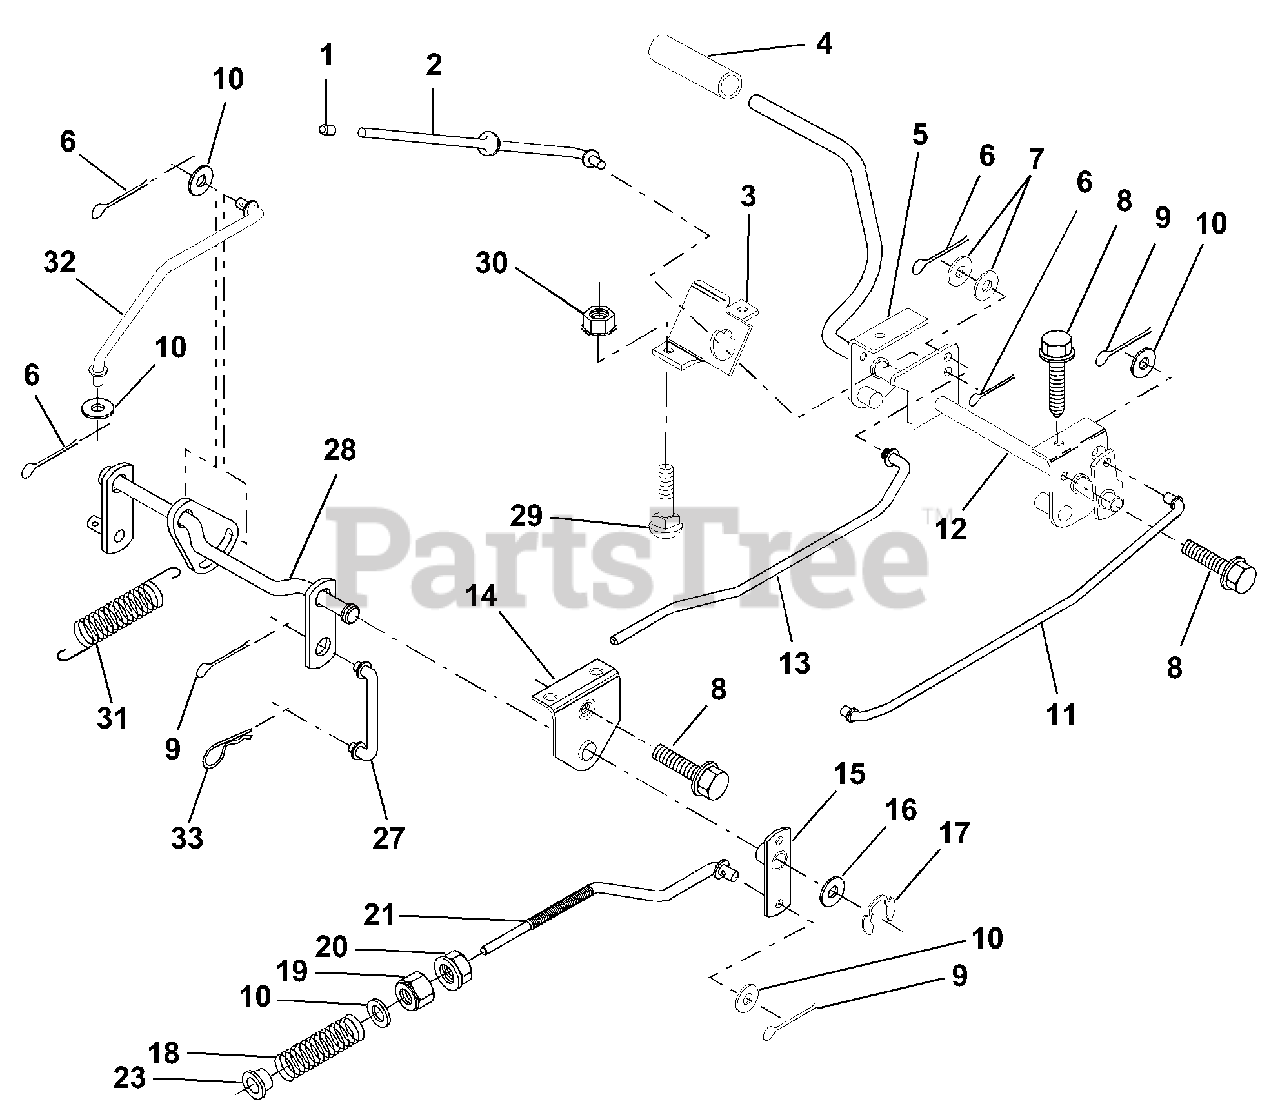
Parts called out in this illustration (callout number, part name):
1	Cap, Plunger
2	Rod, Parking Brake
3	Bracket, Parking Brake
4	Cover, Pedal
5	Bracket, Clutch/Brake Pedal, L.H.
6	Pin, Cotter 3/32 x 3/4
7	Washer 13/32 x 5/8 x 16 Gauge
8	Screw, Hex Hd, Thdrl 5/16-18 x 1/2
9	Pin, Cotter 1/8 x 3/4
10	Washer 13/32 x 13/16 x 16 Gauge
11	Rod, Brake, Front
12	Assembly, Clutch/Brake Pedal
13	Rod, Clutch
14	Bracket, Lift Shaft
15	Assembly, Brake, Pivot, Arm
16	Washer 25/32 x 1-1/8 x 16 Gauge
17	Ring, Klip
18	Spring, Brake Rod
19	Locknut, Hex, w/Wsh Ins 3/8-16 Unc
20	Nut, Hex, Jam 3/8-16 UNC
21	Rod, Brake, Rear
23	Bushing, Link, Drag
27	Link, Lift, Rear
28	Assembly, Rear Mower Lift
29	Bolt, Carriage 5/16-18 UNC x 3/4
30	Nut, Hex, Keps 5/16-16 UNC
31	Spring, Counterbalance
32	Link, Lift Lever
33	Retainer Spring
